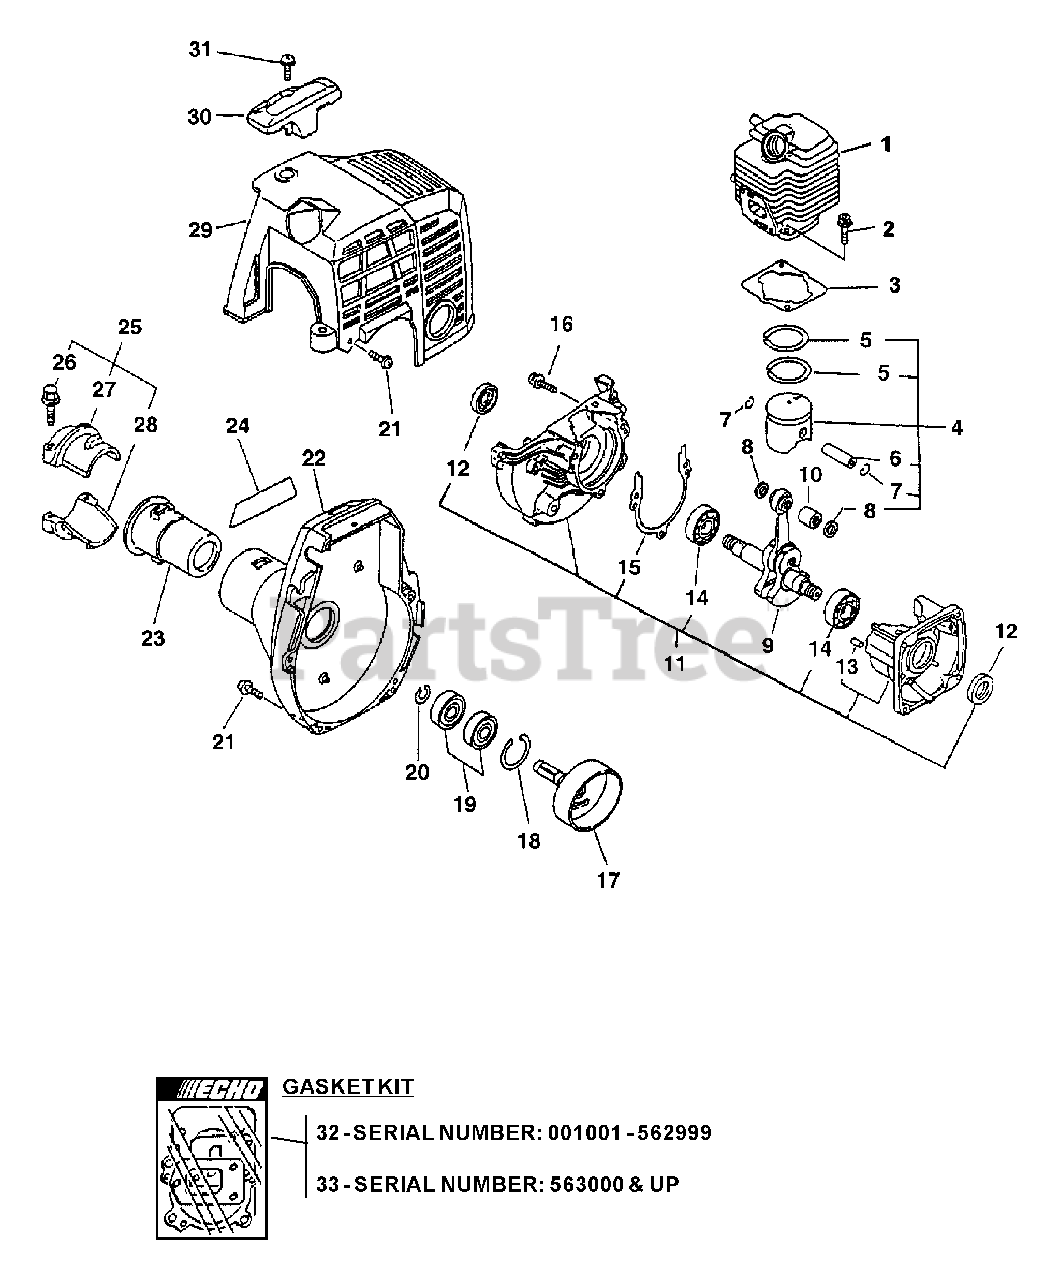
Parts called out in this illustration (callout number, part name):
1	CYLINDER
2	SCREW - 5X22
3	GASKET, CYLINDER
4	PISTON KIT
5	RING, PISTON
6	PIN, PISTON
7	RING, RETAINING
8	SPACER, PISTON
9	CRANKSHAFT ASSY
10	BEARING, NEEDLE
11	CRANKCASE KIT
12	SEAL, OIL
13	PIN - LOCATING
14	BEARING, BALL - 6201
15	GASKET, CYLINDER
16	SCREW - 5X28
17	DRUM, CLUTCH
18	RING, RETAINING - 28
19	BEARING, BALL - 6001
20	RING, RETAINING - 12
21	SCREW - 4X16
22	CASE, FAN
24	LABEL - MODEL
25	MAIN PIPE CLAMP KIT
26	BOLT - 5X25
27	CLAMP, MAIN PIPE - UPPER
28	CLAMP, MAIN PIPE - LOWER
29	COVER, ENGINE
30	GUARD - TOP
31	SCREW - 5X16
32	GASKET KIT
33	GASKET KIT
